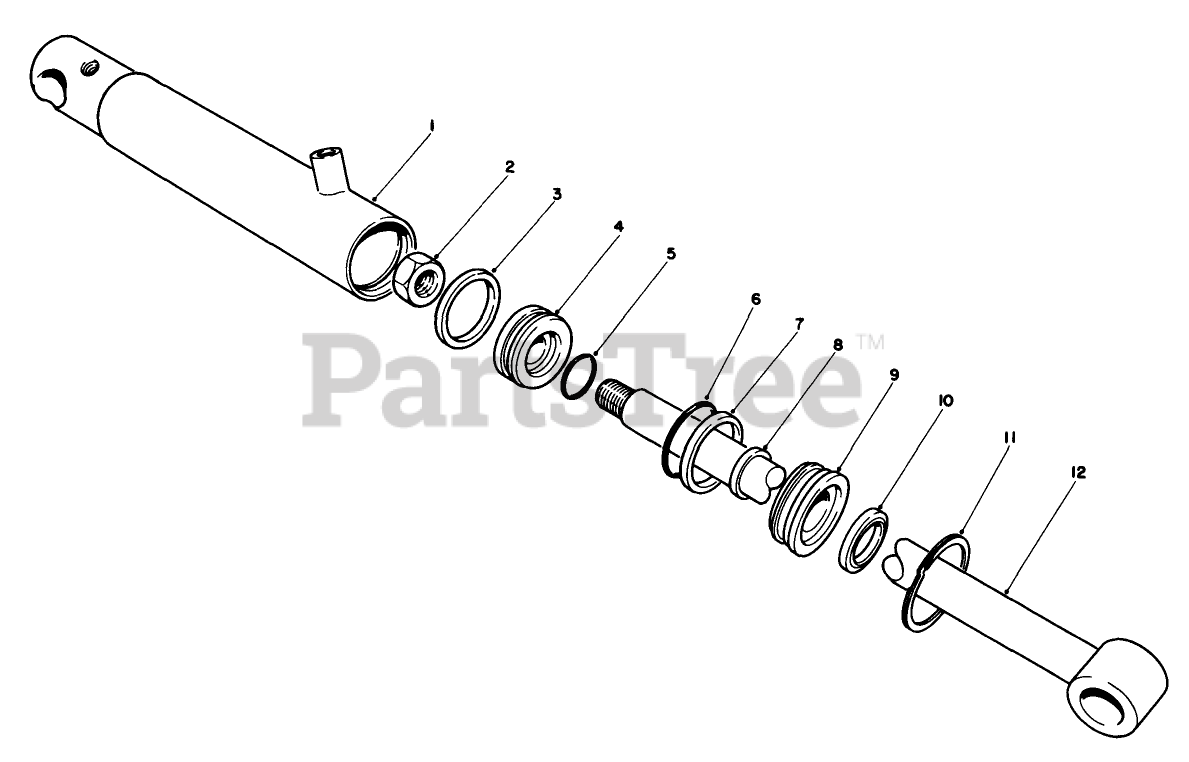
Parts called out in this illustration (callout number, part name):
1	Assembly-Tube
2	LOCKNUT
4	PISTON
6	O-Ring, Head
8	Poly-Pack
11	RING-RETAINING
12	SHAFT W/CLEVIS
